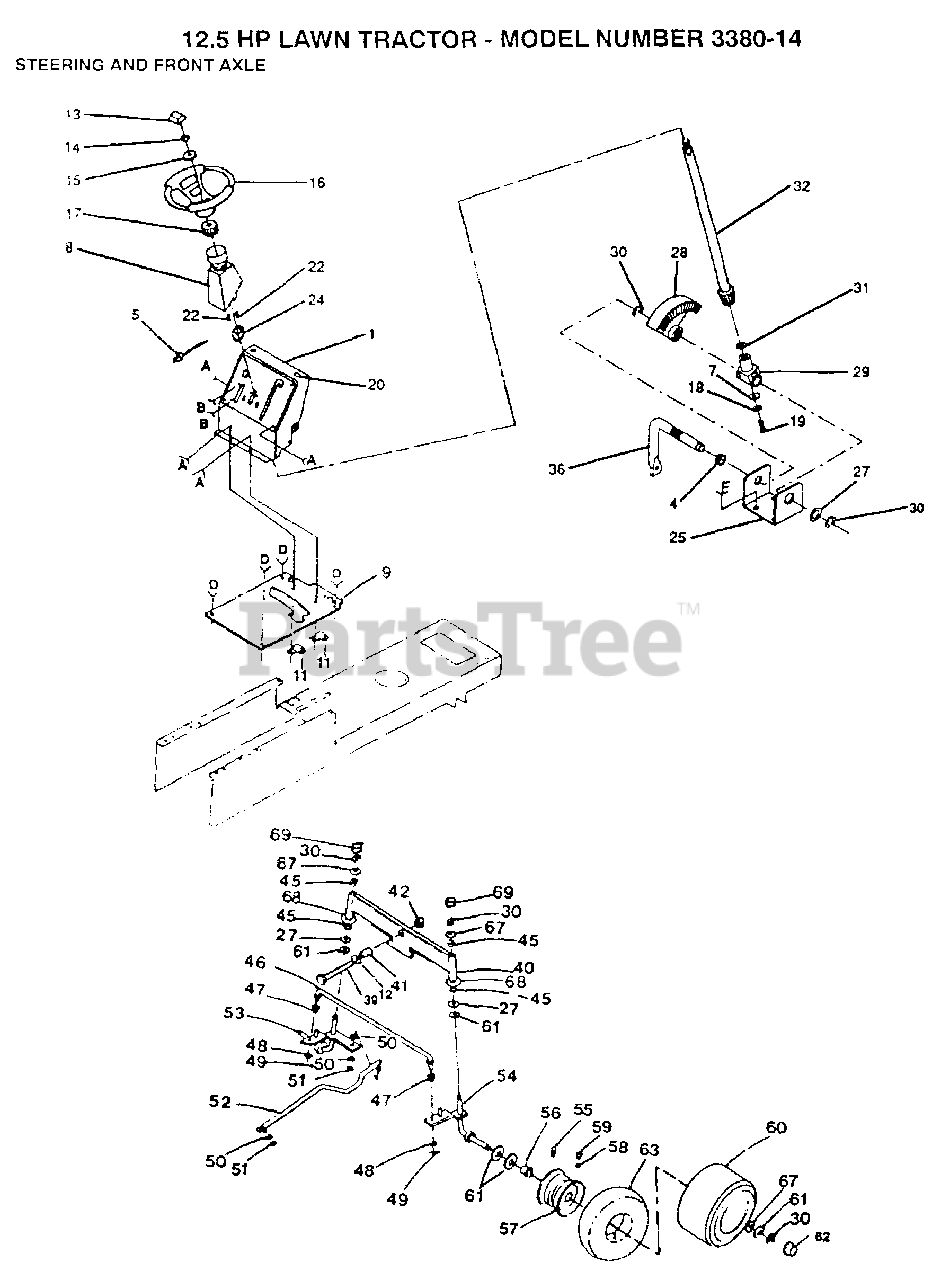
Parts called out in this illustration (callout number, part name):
4	NYLINER T
8	"TUBE, STR SHAFT"
11	CLIP T
13	INSERT-WHEEL LT
15	WASHER
17	ADAPTER LT
18	LOCKWASHER
19	"SCREW,SPECIAL"
24	"BUSHING,STEERING"
25	"BRKT,STEERING"
27	WASHER .T
29	SUPPORT.SHAFT
30	RING
31	THRUST WASHER
32	SHAFT WELD STR T
39	BOLT LT
45	COL. SRTG. BEAR.
48	WASHER
49	COTTER PIN
50	LOCKWASHER
53	SPINDLE-LH LT
55	FITTING LT
56	"FLANGE, BEARING"
58	VALVE CAP
59	VALVE STEM LT
61	WASHER
62	HUB CAP
63	TUBE.5.3/4.5/6
67	WASHER
68	WASHER
69	CAP
